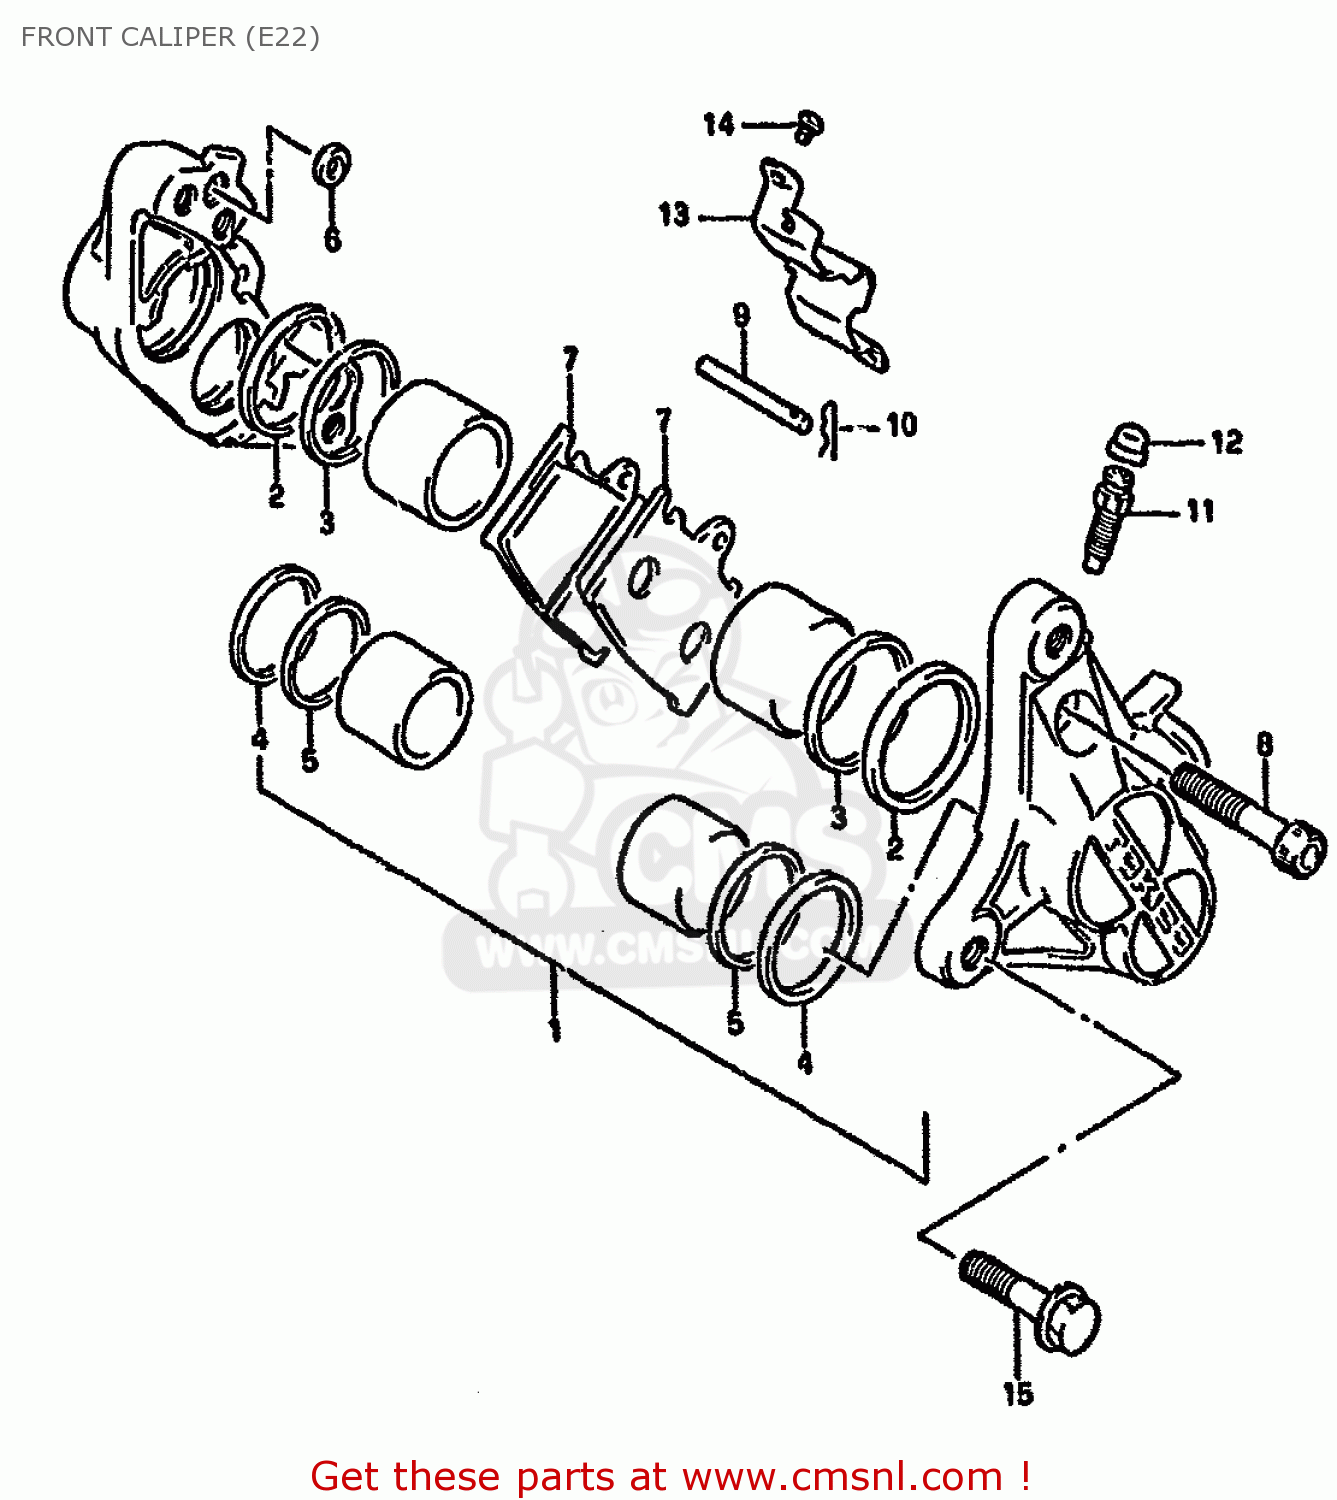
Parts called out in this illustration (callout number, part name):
1	PISTON SET,BRK
2	SEAL,PISTON
3	SEAL,WIPER
4	SEAL
5	SEAL,WIPER
6	SEAL,JOINT
7	PAD
8	BOLT,CALIPER
9	PIN,PAD
10	CLIP,PAD PIN
11	BLEEDER
12	CAP,BREATHER
13	COVER,DUST,R.
14	SCREW
15	BOLT
